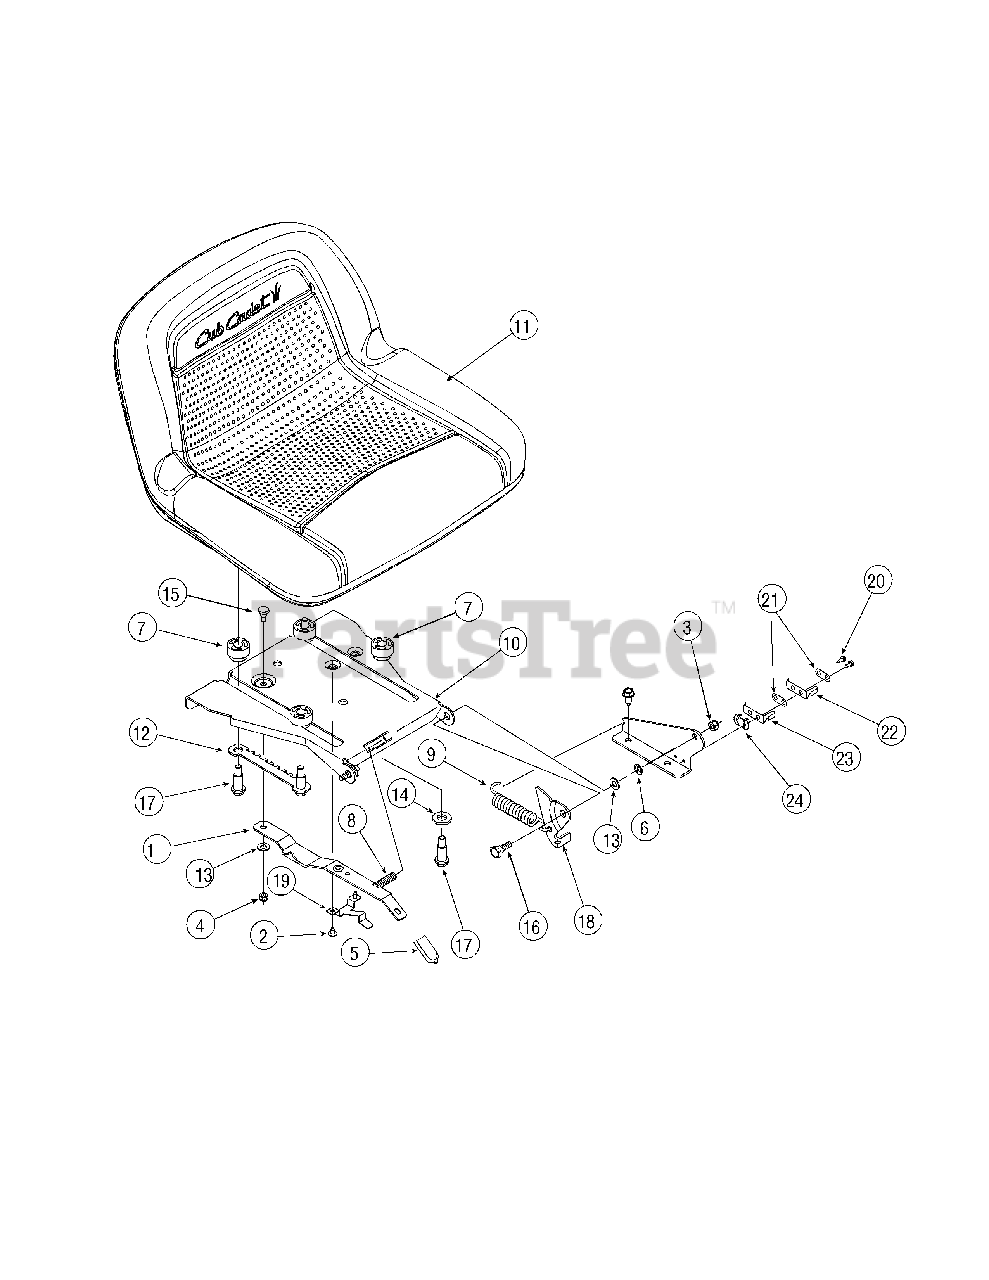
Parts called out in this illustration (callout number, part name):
2	Screw, #10-16, 0.375
3	Nut, Nylon Lock, 5/16-18, Gr5
4	Nut, Nylon Lock, 1/4-20
5	Grip, Seat, Adjustment (Yellow)
6	Nut, Speed,.3125 ID
7	Spacer, Seat, Adjustment
8	Spring, Compression.41 OD x 1.50
9	Spring, Extension,.80 Dia x 4.6 Lg.
12	Selector, Seat, Adjustment
13	Washer, Flat,.344 x.688 x.065
14	Washer, Flat,.531 x 1.062 x.134
15	Screw, Shoulder,.340 x.285, 1/4-20
16	Shoulder, Screw.437 x.286 Lg
17	Screw, Shoulder,.50 x.925, 3/8-16
18	Bracket, Seat Lift
19	Stop, Seat, Adjustment
20	Screw, #8-18 x.50
21	Plate, Insulator
22	Spring Switch, Outer
23	Spring Switch, Inner
24	Plate, Insulator Boss
